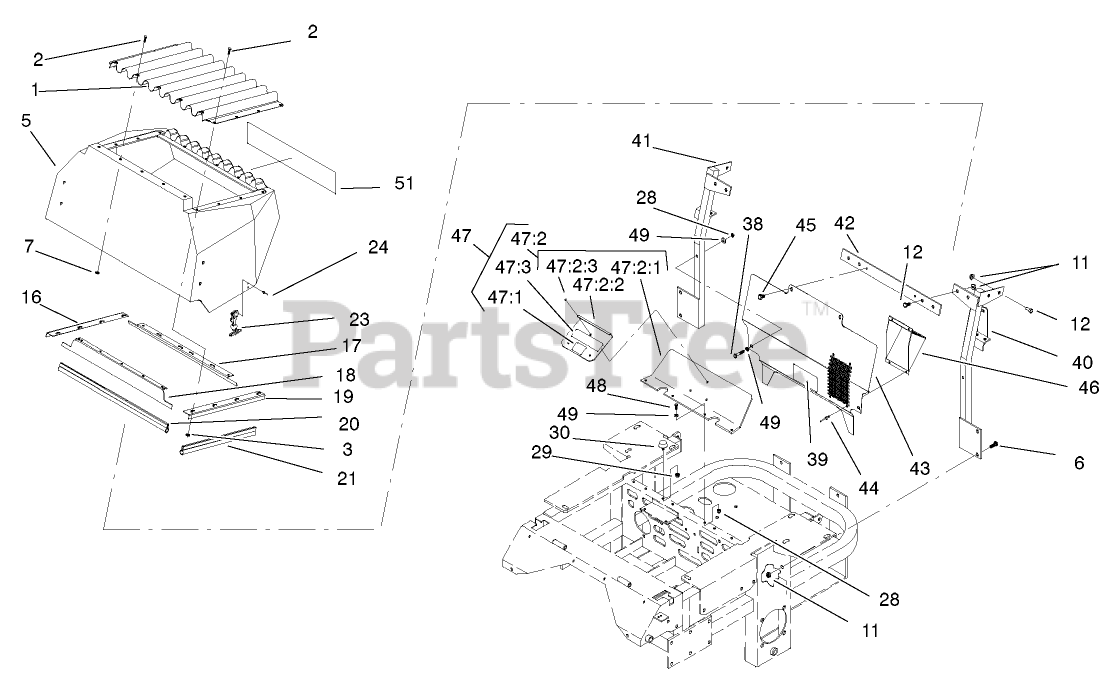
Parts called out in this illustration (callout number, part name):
1	SCREEN-RADIATOR
3	WASHER-FLAT
6	SCREW-HH
7	WASHER-SPRING
11	NUT-HF
12	SCREW-HH
16	ANGLE-RADIATOR, RH
17	ANGLE-RADIATOR, BOTTOM
18	ANGLE-RADIATOR, TOP
19	ANGLE-RADIATOR, LH
20	SEAL-TRIM
21	SEAL-TRIM
23	LATCH-RUBBER
24	RIVET
28	NUT-LOCK, NI
29	NUT-HF
30	BUMPER
38	SCREW-HH
39	DECAL-ROUTING, BELT
40	BRACE-RADIATOR, LH
41	BRACE-RADIATOR, RH
42	CROSSBAR
43	DEFLECTOR-AIR
44	RIVET-POP
45	SCREW-HWHTF
46	PLENUM-INTAKE, AIR
47	SHIELD ASM
47:1	DECAL-IMPORTANT
47:2	SHIELD AND LIFT ASM
47:2:1	SHIELD-ENGINE
47:2:2	LIFT-SHIELD
47:2:3	RIVET-POP
47:3	DECAL-DEVICES, ROTATING
48	SCREW-HH
49	WASHER-FLAT
51	DECAL-Z MASTER LIQUID COOLED
